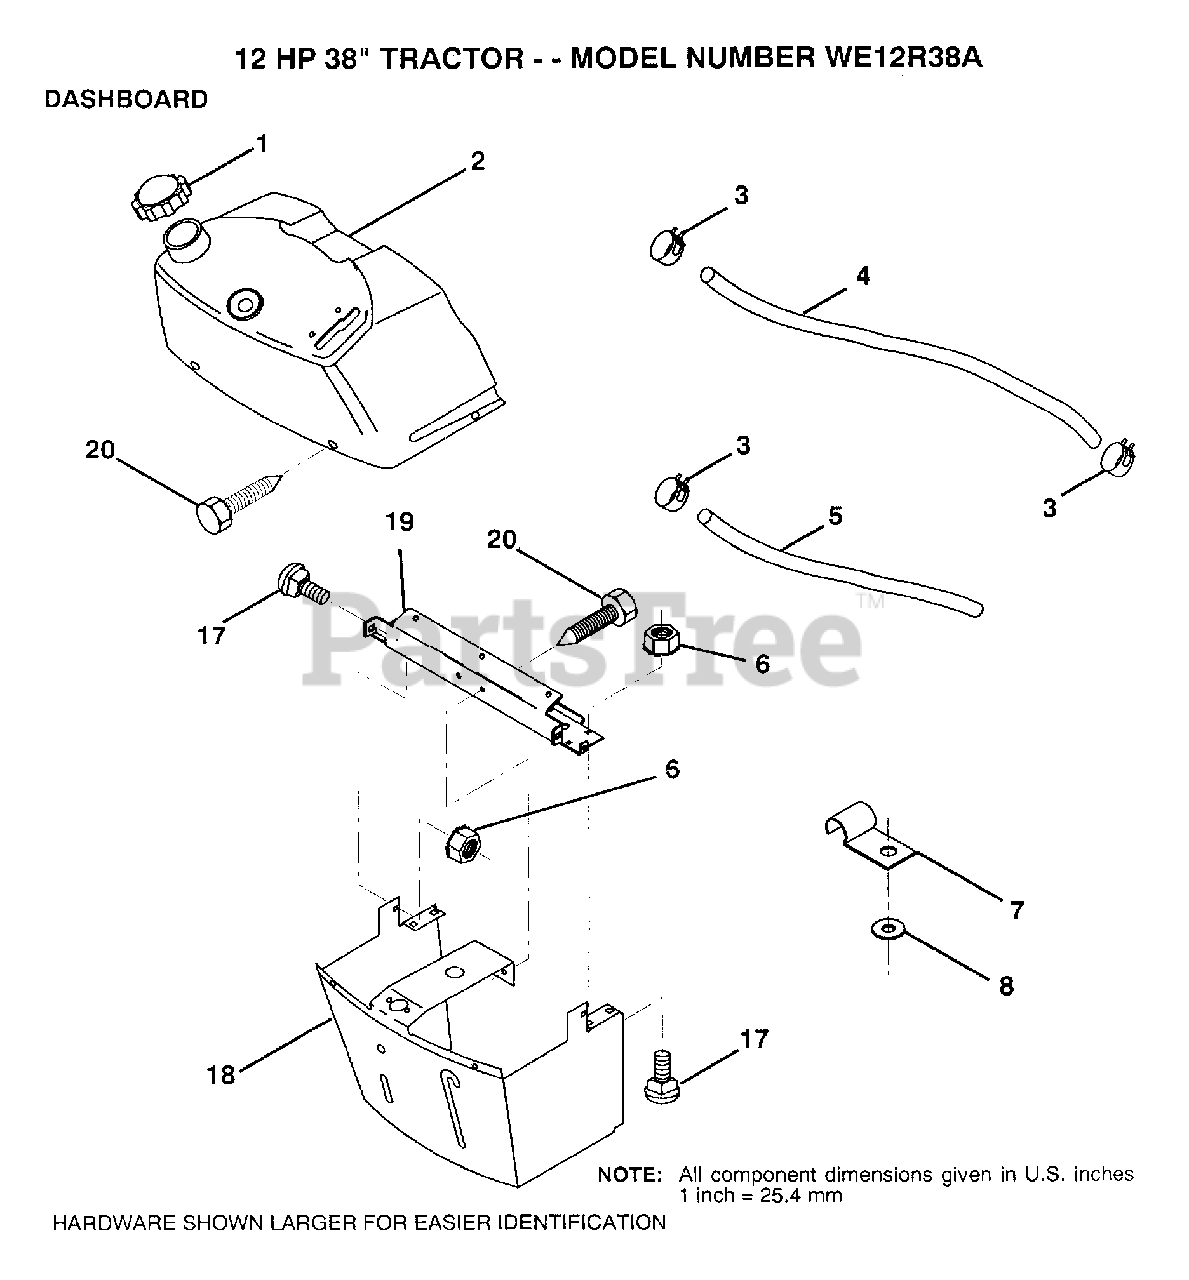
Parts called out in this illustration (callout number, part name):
1	CAP.FUEL.N/VENT
2	TANK.ASM.DASH.LR
3	HOSE CLAMP
5	FUEL LINE T
6	NUT
7	CLIP T
8	WASHER PM
17	BOLT
18	SUPT ASM DASH
19	CROSS BRACE
20	SCREW.1/4-20X1/2
